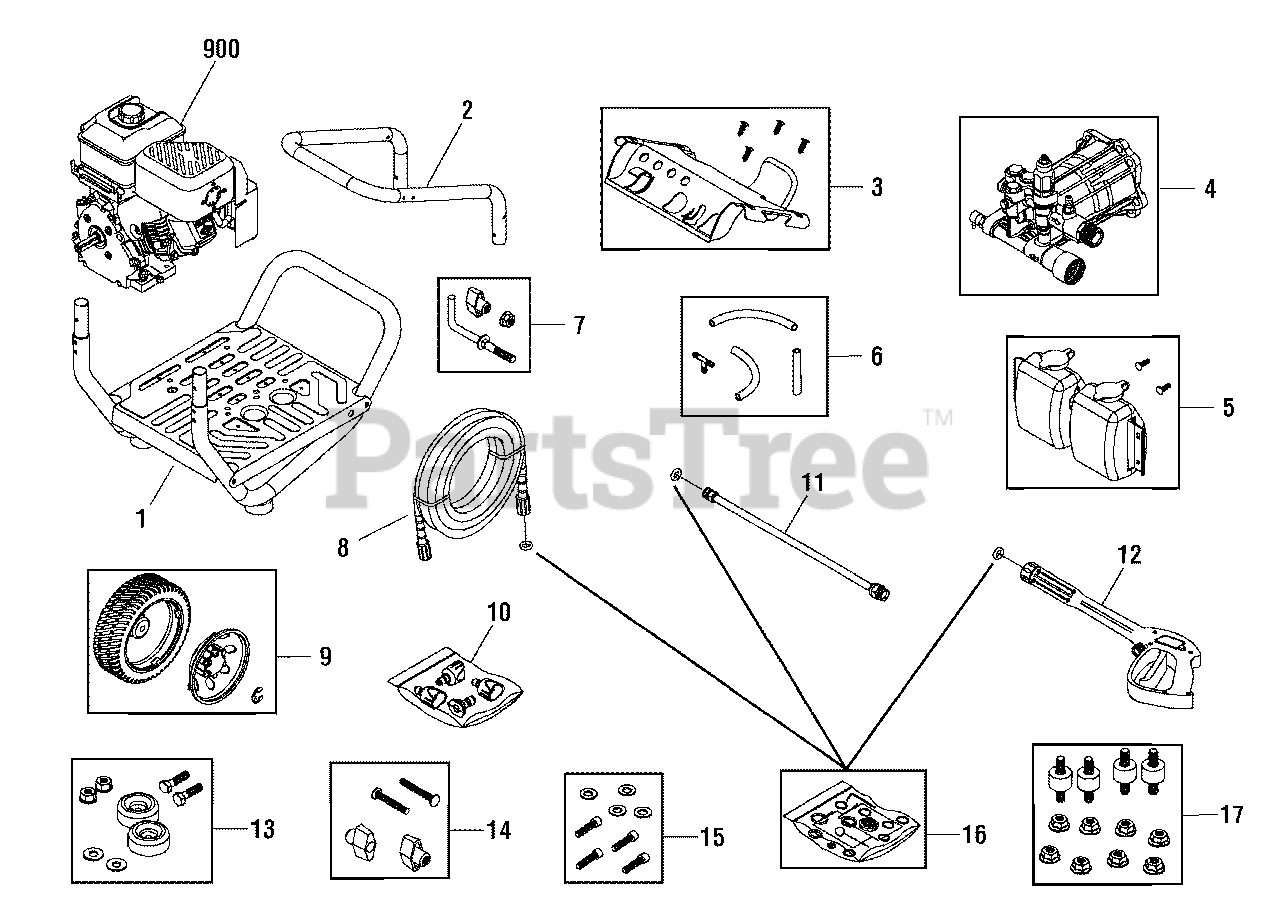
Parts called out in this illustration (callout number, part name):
4	PUMP
6	KIT, Chemical Hose
8	HOSE
10	KIT, QC Nozzles
11	EXTENSION, QC
12	GUN
13	MOUNT, Vibration
14	KIT, Hardware, Handle
15	KIT, Hardware, Pump Mounting
16	KIT, O-Ring
17	KIT, Vibration Mount
900	* ENGINE
